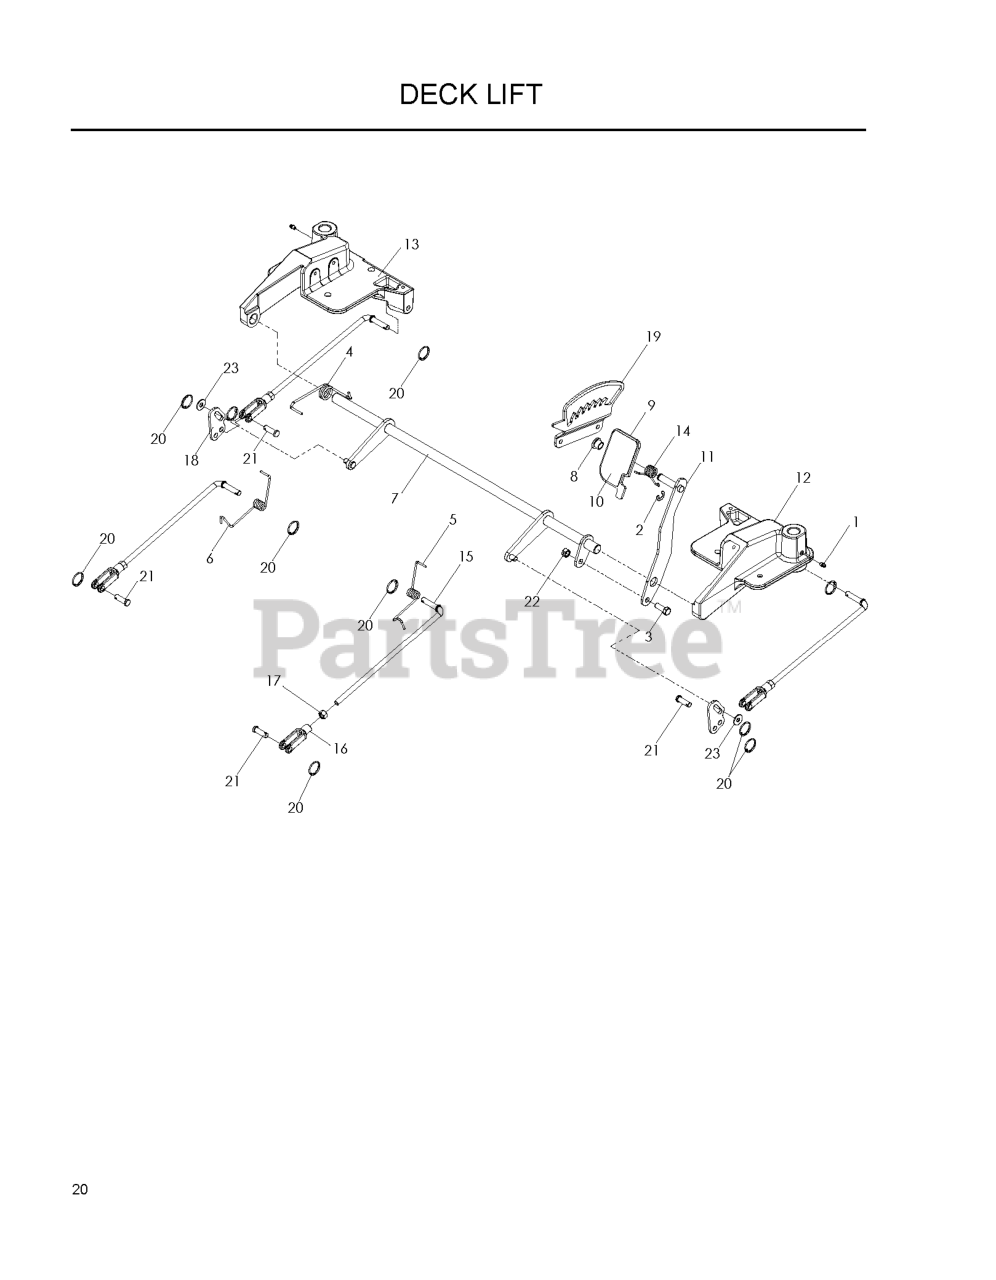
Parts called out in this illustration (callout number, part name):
2	E-RING 1/2 (2 2)
3	HEX BOLT 3/8 X 1"
4	TORSION SPRING, DECK LIFT
5	SPRING, DECK ROD RIGHT
6	SPRING, DECK ROD LEFT
7	DECK LIFT ASM PAINTED
8	BUSHING, FLANGED NYLON
9	FOOT PEDAL
10	FOOT PAD, NON-SLIP
11	LIFT FOOT, LEVER WELDED
12	CASTER CASTING, RIGHT, PAINTED
13	CASTER CASTING LEFT, PAINTED
14	SPRING, PEDAL, LIFT
15	DECK LIFT ROD
16	YOKE-3/8-24 PLTD
18	CONNECTOR, DECK LIFT
19	HEIGHT PLATE, DECK
21	CLEVIS PIN 3/8 X 1 1/8
22	NUT 3/8C CENTERBLOCK
23	WASHER 5/16 FLAT
